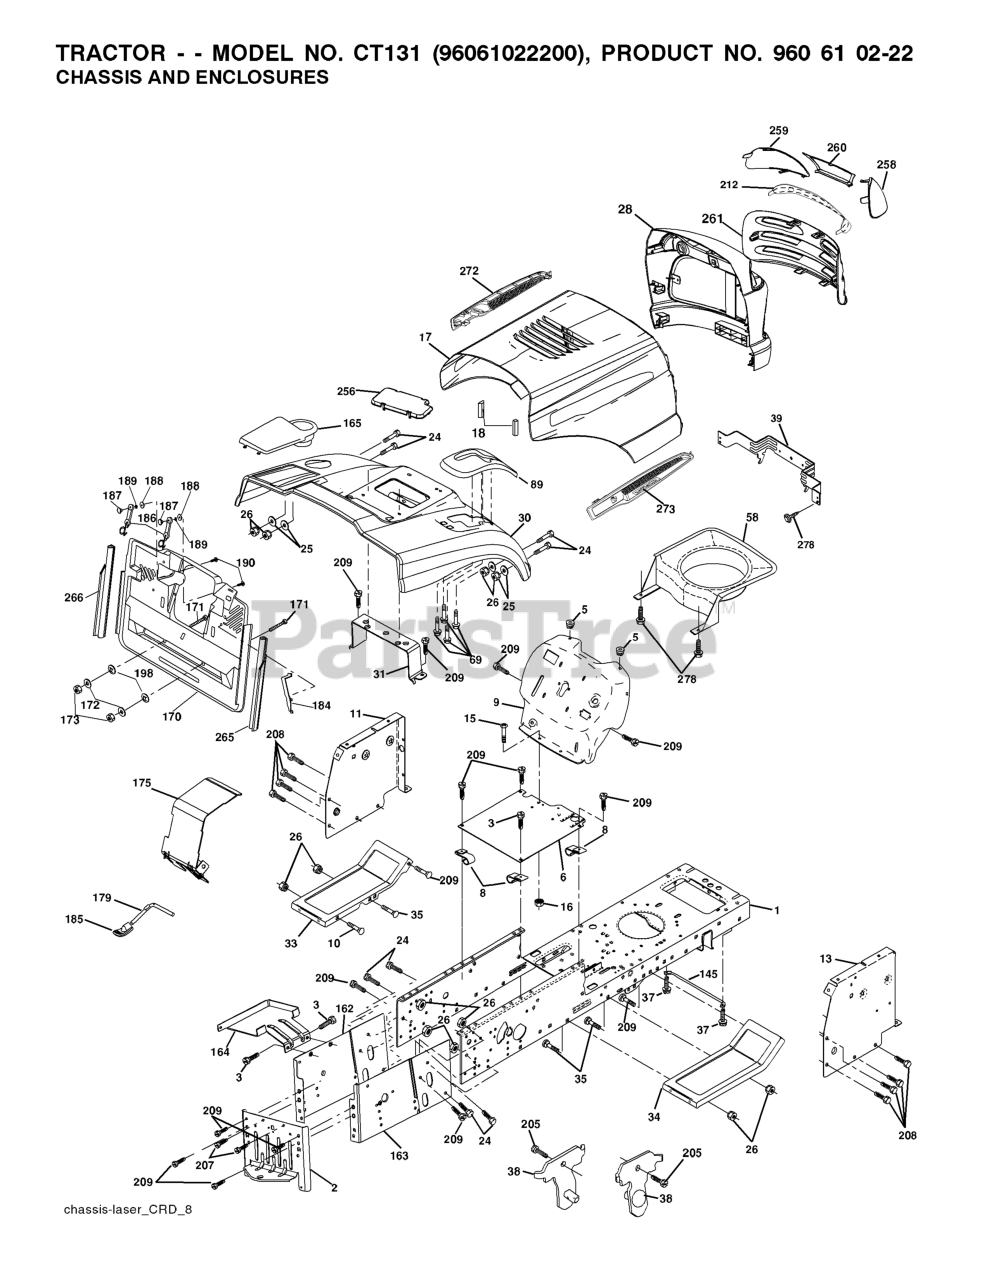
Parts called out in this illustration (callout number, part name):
2	DRAWBAR
3	SCREW 3/8-16X3/4
5	BUMPER.RUBBER.HOOD
6	PLATE
8	CLIP,INSULATOR
9	DASH.SLK.LT.PL.CC.NA.NHM.CE
10	BOLT D
11	PANEL.DASH.LH.LTX
13	PANEL ASM, DASH RH
15	Screw, Machine, Truss Head 5/16-18 UNC x 3/4
16	NUT
17	VENT.HOOD.LASER.III
18	BUMPER.HOOD.LARGE.1.75"
25	WASHER
26	NUT
30	CONSOLE.CRD.AUTO.GRY
31	BRACKET SUPPORT FENDER
33	FOOTREST.LH.BLACK
34	FOOTREST.RH.BLACK
37	Screw 5/16-18 x 1/2 Hex, Self Tapping 5/16-18 x 1/2
38	BRACKET ASM PIVOT MOWER REAR
39	BRACKET PIVOT
69	SCREW.HI-LO.CONSOLE
89	CONSOLE.CRD.6SP.BLACK
145	ROD.PIVOT.HOOD
162	BRACKET
163	BRACKET EXTEN CHASSIS RH CRD
165	COVER.BATTERY.CRD.BLACK
172	WASHER
175	DOOR TRAP
179	ROD PIVOT FBI
184	BRACKET.ACTUATOR.BAGGER.SRD
186	LATCH ASSY
187	WELDNUT
189	LOCKWASHER #10
190	SCREW
207	SCREW, 5/16-18 X 1/2
208	SCREW 3/8-16X1/2
209	SCREW, 3/8-16X3/4
212	INSERT.LENS.REFLECTIVE
256	COVER FENDER CRD
258	LENS LH
259	LENS LH
260	COVER.LENS.HUSQ.LASER
265	SEALING
266	SEALING
272	VENT.HOOD.LASER.
273	VENT.HOOD.LASER.
278	SCREW
